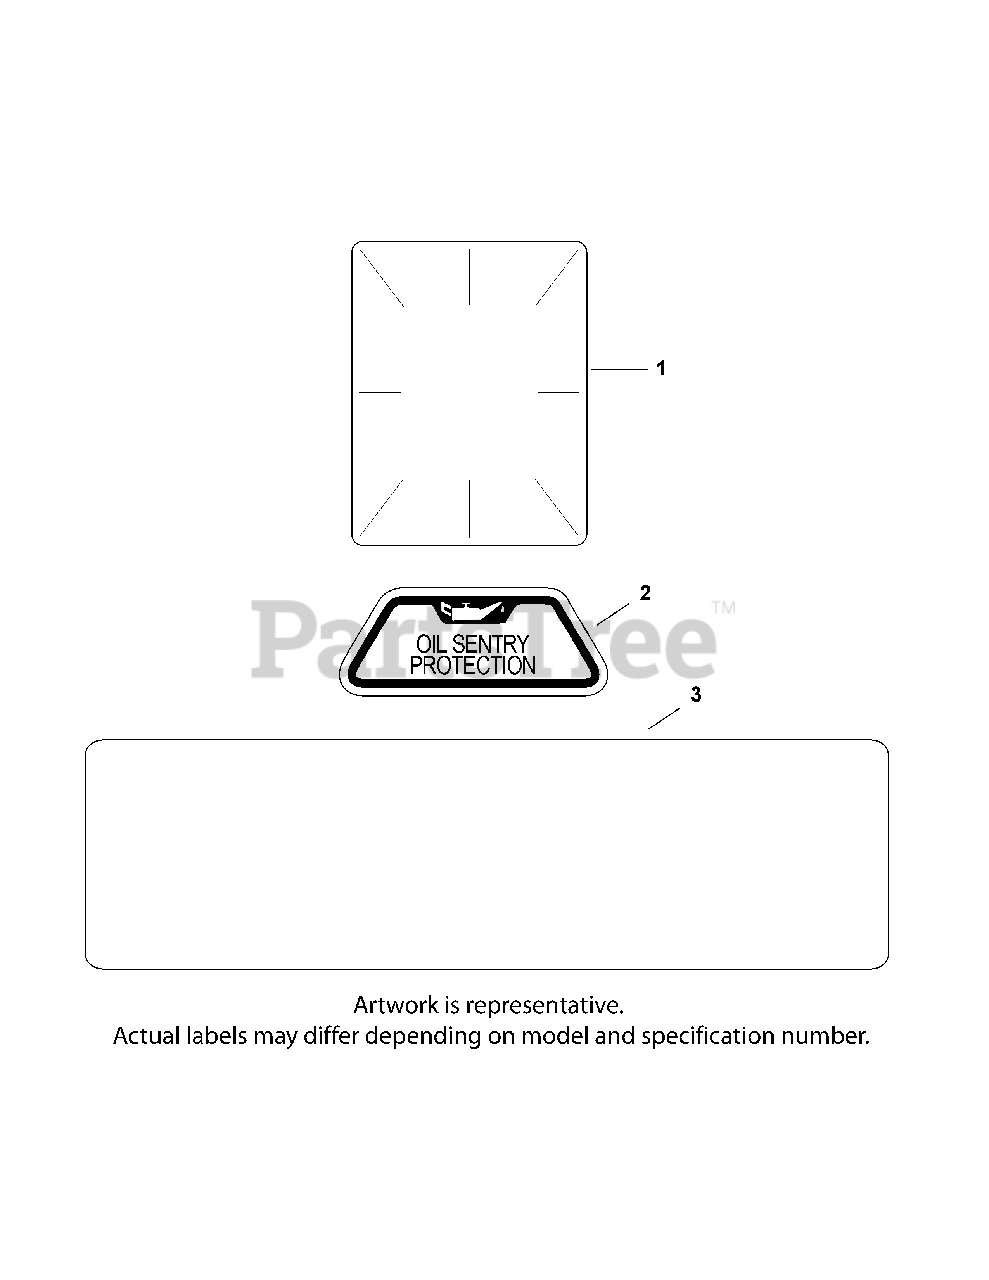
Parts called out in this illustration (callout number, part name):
1	Decal, Clear Laminate
2	Decal, Oil Sentry
3	Decal,HP (20)
